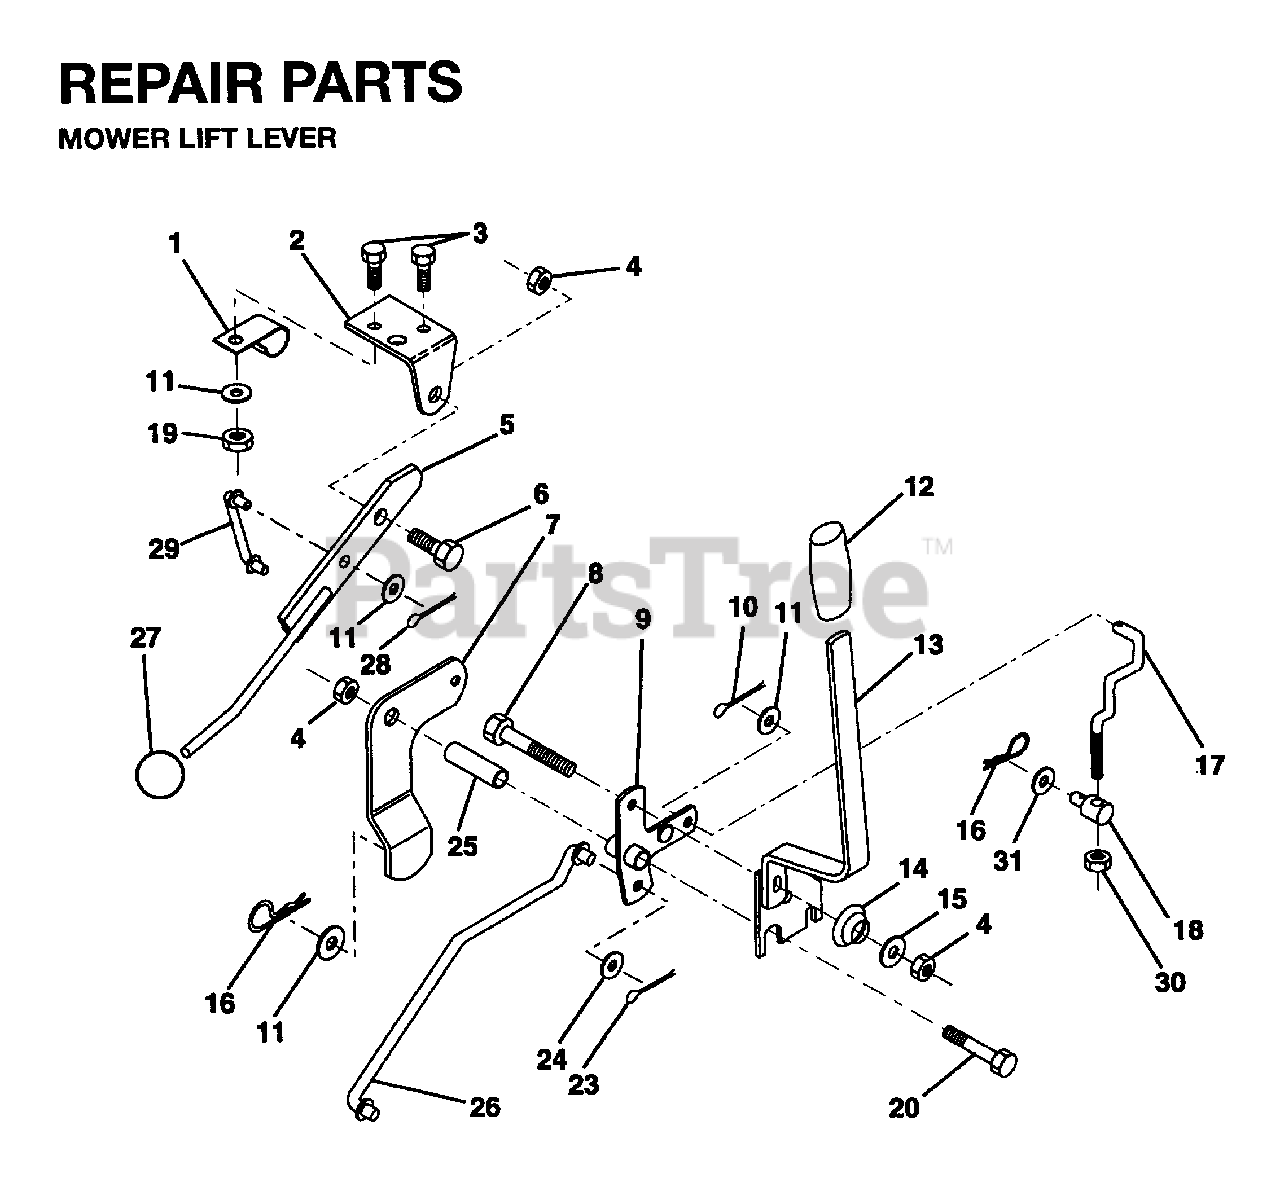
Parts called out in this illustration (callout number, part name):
1	CLIP,INSULATOR
2	BRKT CLUTCH
3	BOLT
4	LOCKNUT
5	CLUTCH LEVER
6	BOLT, SHOULDER LT
7	ASSEMBLY MOWER CLUTCH ARM
9	BELLCRANK,LIFT
10	COTTER PIN
11	WASHER
12	GRIP HANDLE
13	LIFT HANDLE ASSY
14	SPRING COMPRESSIO
15	WASHER
16	SPRING.RETAINER
17	LINK LIFT FRT
19	NUT.CROWNLOCK.1/4
23	PIN COTTER
24	WASHER - M12
25	TUBE SPACER
27	KNOB
28	COTTER PIN
29	LINK MOWER CLUTCH
30	NUT.HEX.3/8-16UNC
